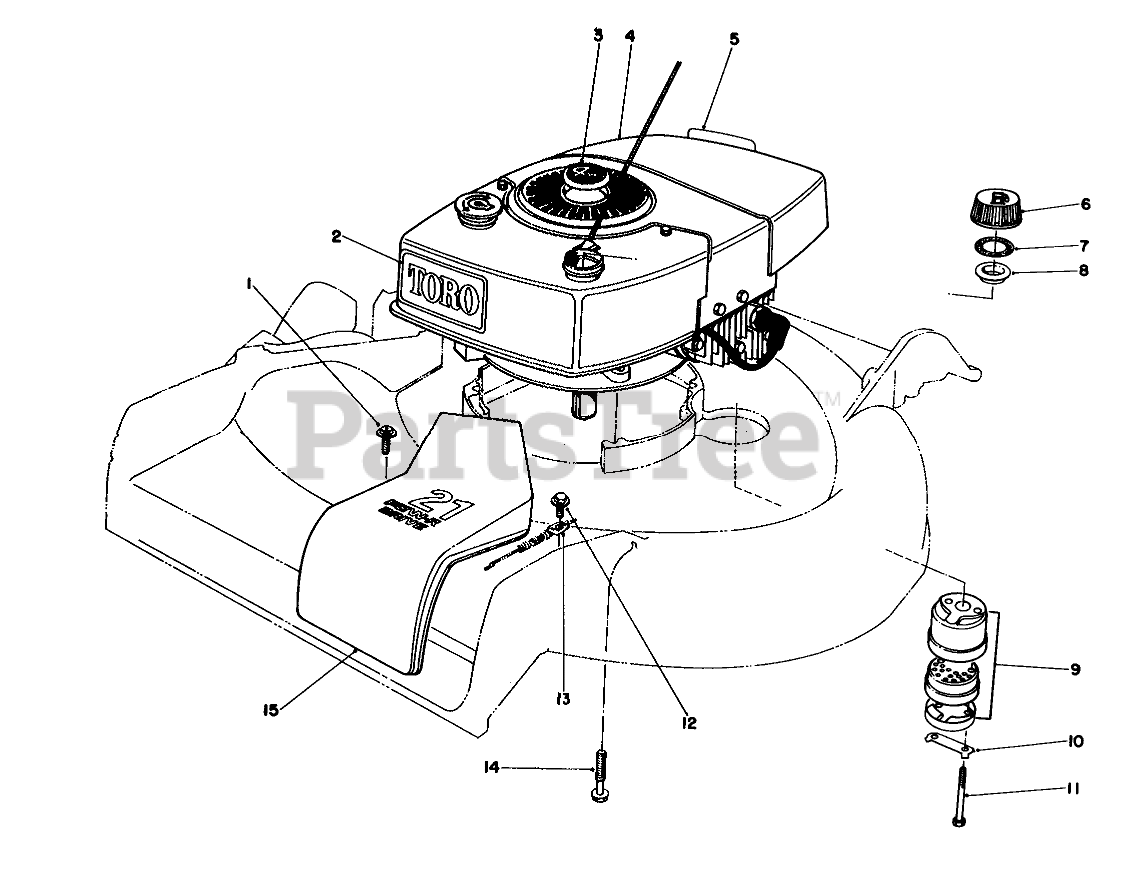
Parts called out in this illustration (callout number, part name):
1	SCREW
2	Decal Tow
3	PLUG BUTTON
4	Engine
5	Decal-Maintenan
6	Gas Cap Assembly (Incl. Ref. #7 & 8)
7	GASKET
8	GAS CAP BAFFLE
9	Muffler Assembly (Incl. #10 & 11)
10	CLIP - LOCKING
11	SCREW-HH
12	SCREW-HWHTF
13	Cable Clamp
14	3/8-16 X 2-3/4 CAPSCR
15	Cover-Belt
